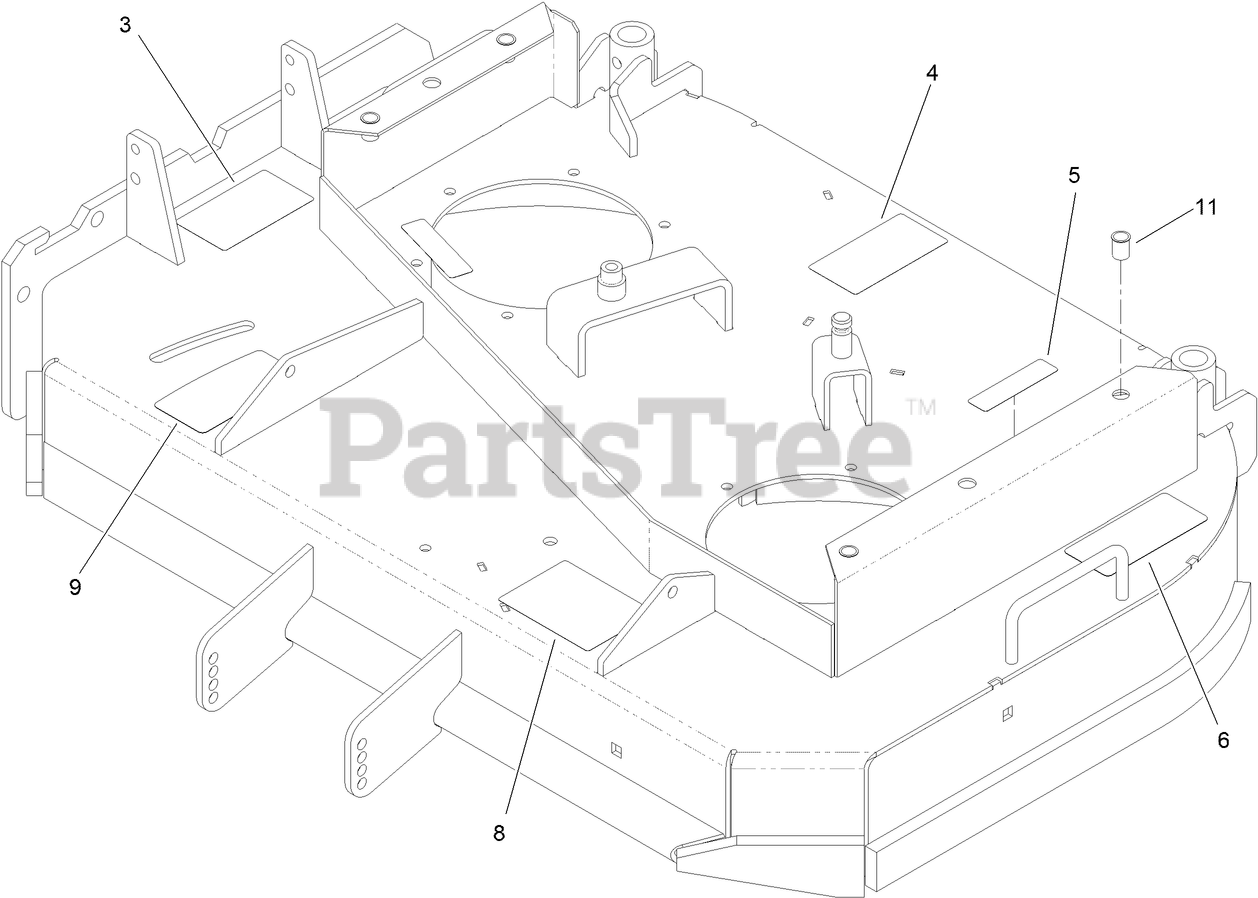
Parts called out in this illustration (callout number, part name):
3	DECAL-DANGER
5	DECAL-DANGER
6	DECAL-TORQUE, BLADE BOLT
8	DECAL-ANTI SCALP
9	DECAL-ADJUSTMENT, BAFFLE
11	NUT-CLINCH
